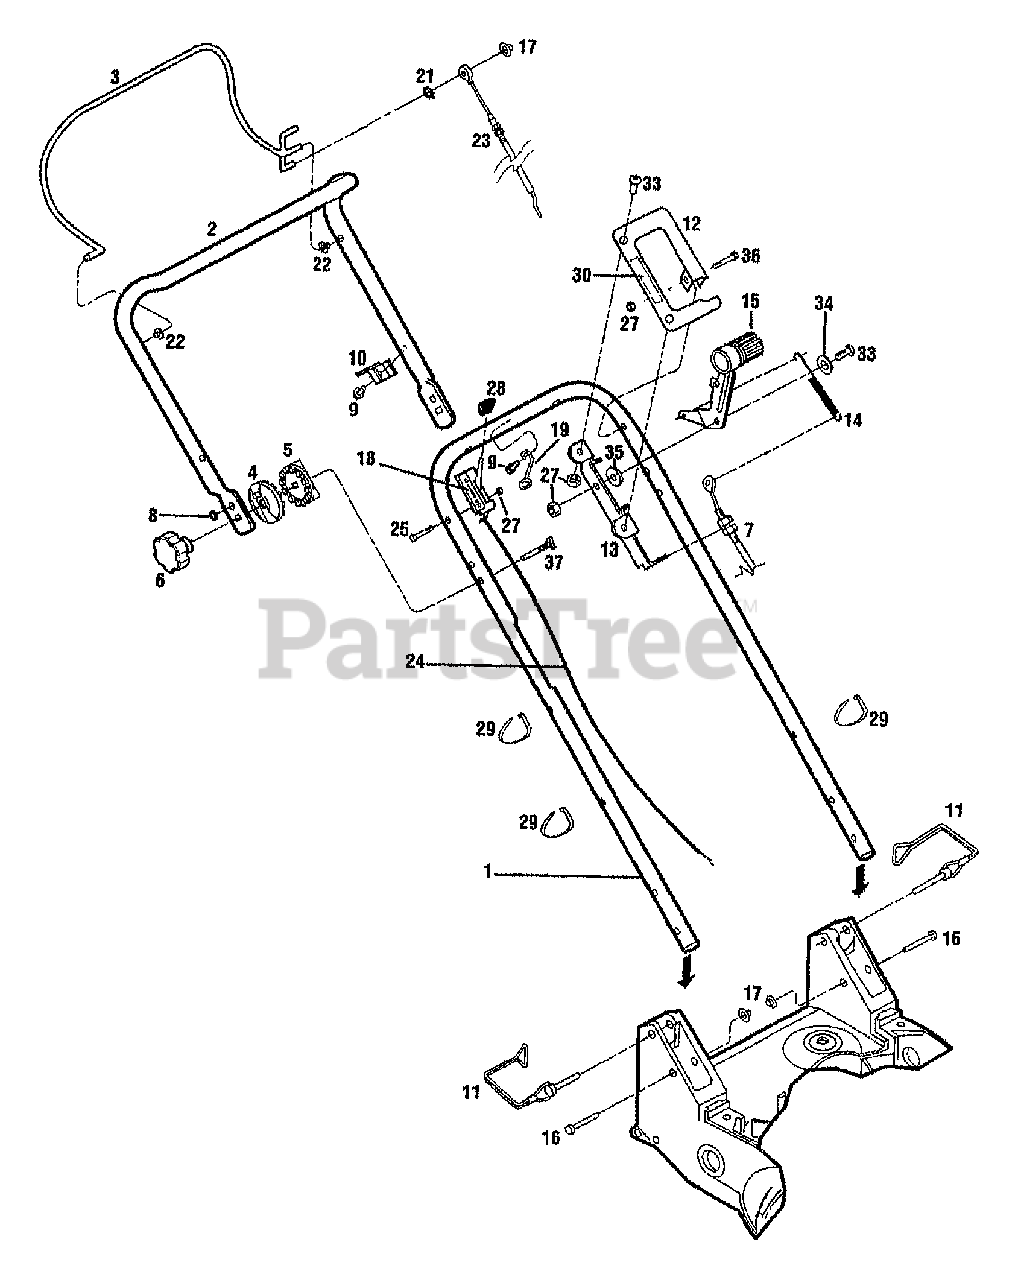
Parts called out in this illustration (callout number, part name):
1	HANDLEBAR-LOWER PNT
2	HANDLEBAR-UPR PNT
3	BAIL-CONTROL VINYL COATED
4	QUADRANT-OUTER
5	KIT-QUADRANT INNER
6	KNOB-HANDLEBAR
9	SCR-FLANGE 1/4-20X3/4 GR5
10	BRKT-CONTROL CABLE
11	PIN-LK SQ. #W51620LP
12	MOUNT-DRIVE CONTROL {34321,34321C}
13	SUPT-CONTROL DRIVE {34321,34321C}
14	SPRING-EXTENSION {34321,34321C}
15	ARM-CONTROL {34321,34321C}
16	PIN-CLEVIS ( @DEPL)
17	CAP-PUSH .312
18	DECAL-ENGINE SPEED
19	GUIDE-ROPE
21	GRIP-RING EXT .312 ID
22	BUSHING-PLASTIC (BAIL)
23	CABLE-ENGINE BRAKE
24	CONTROL-THROTTLE
25	HEX CAP SCREW, 1/4-20x1-3/4
27	TOPLOCK NUT, 1/4-20
28	KNOB-WHEEL DRIVE CABLE
29	TIE-CABLE (REUSABLE)
30	DECAL-WHEEL DRIVE {34321,34321C}
33	SCR-RH 1/4-20X.75 {34321,34321C}
34	WASHER-BELLEVILLE {34321,34321C}
35	BUSHING-NYLON {34321,34321C}
36	SCR 1/4-20X1.5 PL CSHH {34321,34321C}
37	SCR-CURVED HD 5/16-18X2.0
